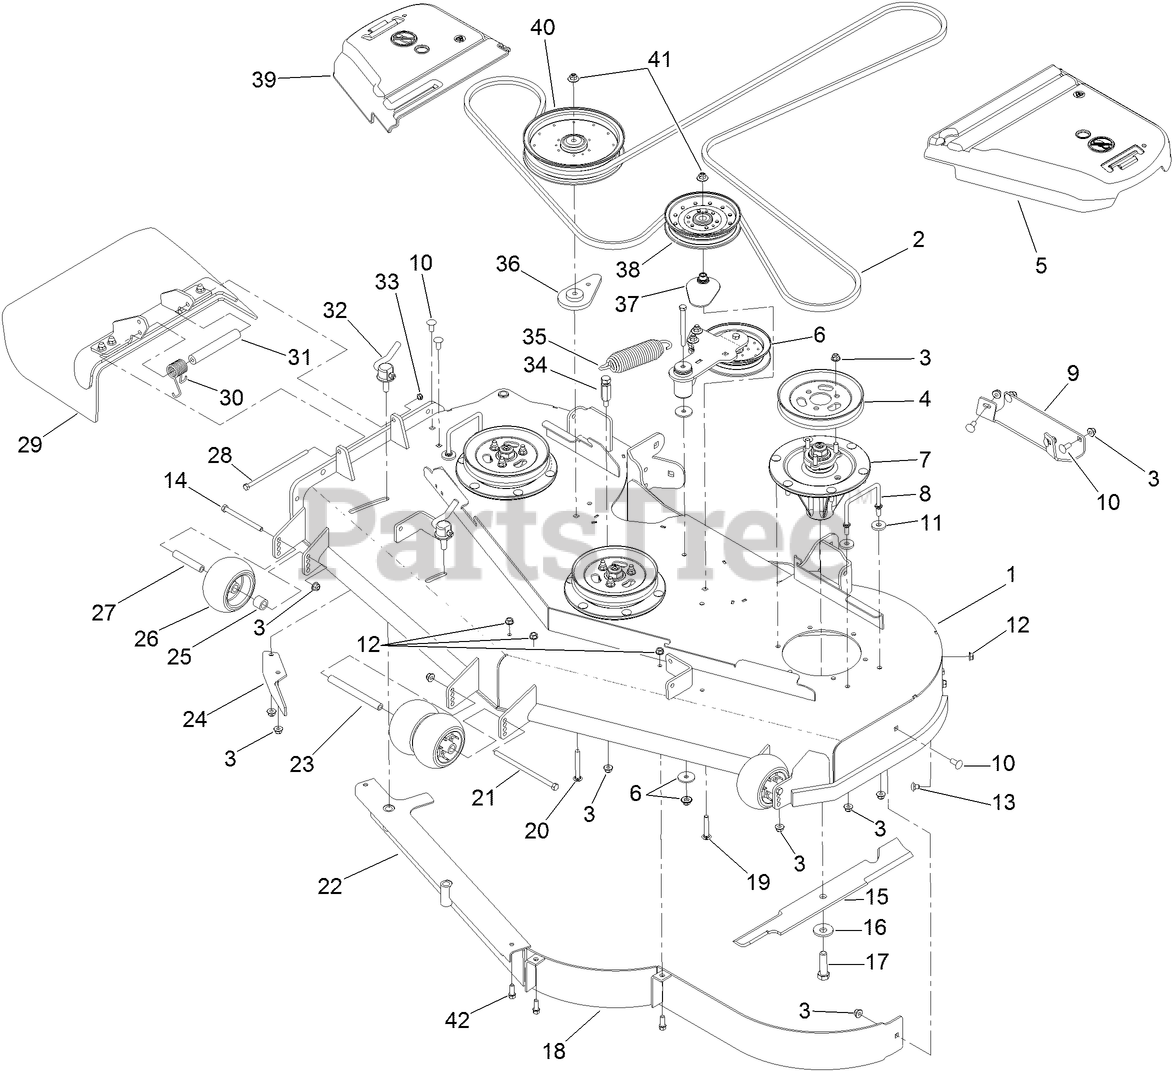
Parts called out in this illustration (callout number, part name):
1	DECK DECAL ASM
2	BELT-V
3	NUT-HF, NI
4	Pulley
5	COVER-BELT, LH
6	IDLER ARM ASM
7	SPINDLE ASM
8	WIREFORM-COVER
9	Plate-Skid
10	SCREW-CARR
11	WASHER
12	NUT-HHF, WHIZ
13	SCREW-CARR
14	SCREW-HH
15	BLADE-HI FLOW
16	Washer-Blade Bolt, Heavy
17	SCREW-BLADE
19	BOLT-CARR, SHORT NECK
20	SCREW-CARR
21	SCREW-HH
23	SPACER-WHEEL
24	BAFFLE-DISCHARGE
25	TUBE-SPACER
26	ROLLER-SCALP, ANTI
27	TUBE-SPANNER
28	SCREW-HH
29	RUBBER DEFLECTOR ASM
30	SPRING-TORSION
31	SPACER
32	LEVER ASM
33	NUT-LOCK, NI
34	ANCHOR-SPRING, TALL
35	EXTENSION-SPRING
36	SPACER-IDLER
37	SPACER-PULLEY
38	PULLEY-IDLER, FLAT
39	COVER-BELT, RH
40	PULLEY-IDLER
41	NUT-FLANGE, NI
42	SCREW-HWH
